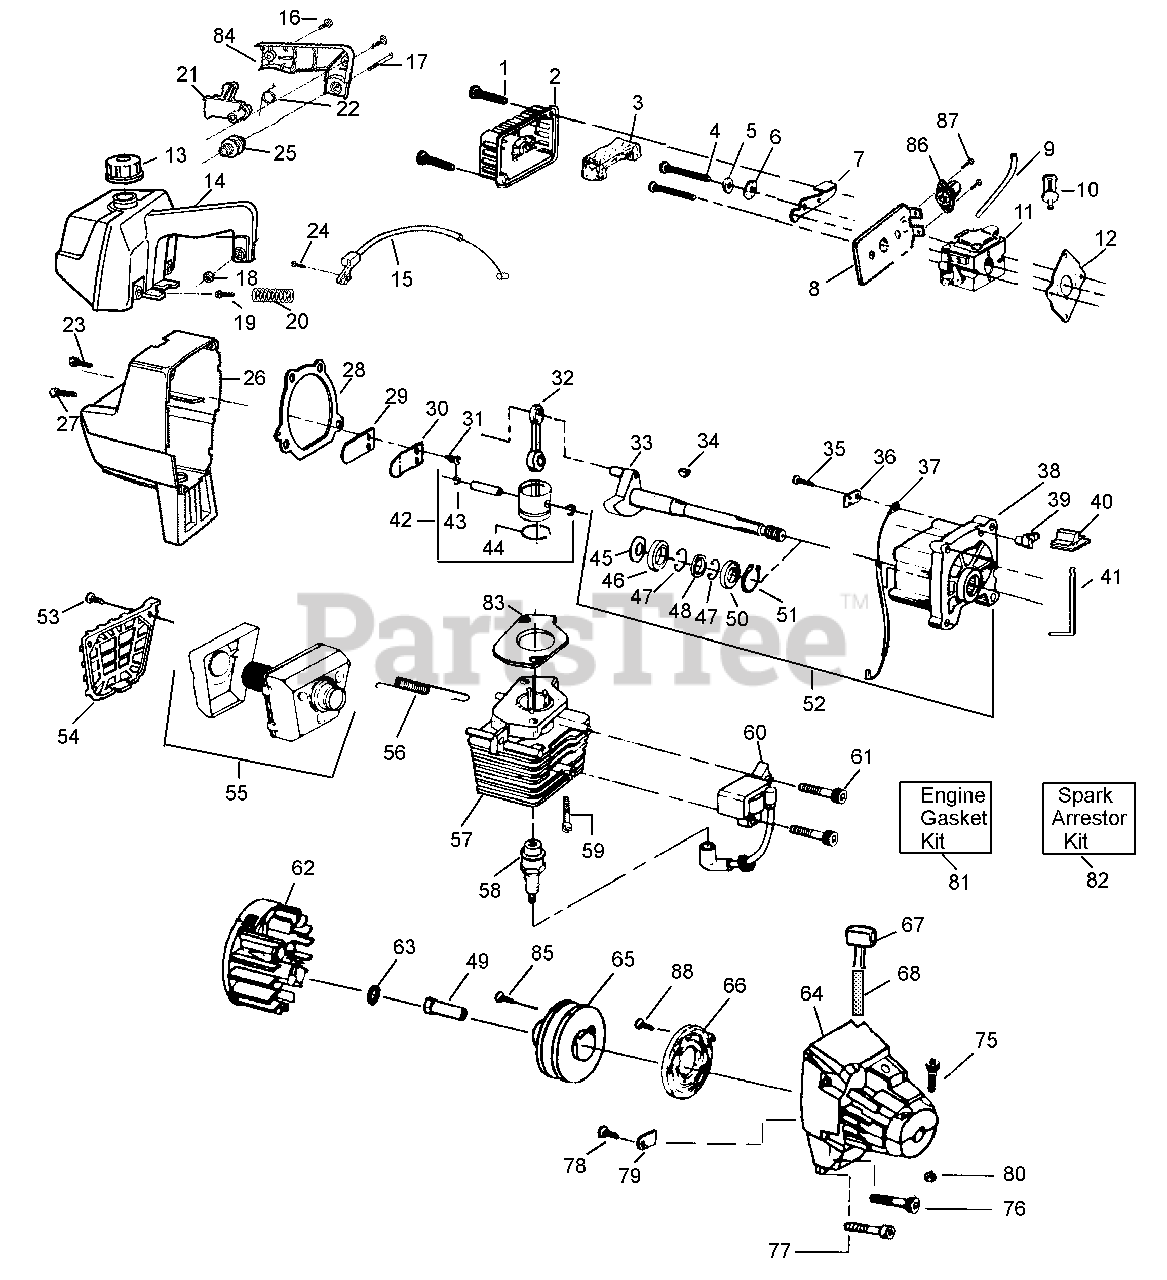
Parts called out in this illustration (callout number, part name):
2	Air Filter Cover
3	Air Filter
6	Wave Washer
7	Choke Shutter
8	Air Filter Plate Type 1
8	Air Filter Plate Type 2 & 3
9	Fuel Line Kit - Fuel Line
9	Fuel Line Kit - Return Line Type 2 & 3
10	Fuel Pick-up Ass'y.
11	Carburetor Type 1 (WA-217)
11	Carburetor Type 2 & 3 (WA-219B)
12	Carburetor Gasket
13	Fuel Cap Ass'y.
14	Handle & Tank Ass'y. Type 1
14	Handle & Tank Ass'y. Type 2 & 3
15	Throttle Cable Ass'y. Type 1
15	Throttle Cable Ass'y. Type 2 & 3
16	Screw
20	Rear Isolator Spring
21	Throttle Trigger
22	Throttle Spring
23	Screw
25	Isolator
28	Gasket
30	Reed Stop
32	Connecting Rod Ass'y.
33	Crankshaft Ass'y.
34	Flywheel Key
36	Switch Insulator
37	Lead Wire
38	Crankcase Ass'y.
39	Switch Ramp
40	Switch Button
41	Switch Spring
42	Piston Kit
43	Piston Pin Retainer
44	Piston Ring
45	Spacer
46	Inner Bearing
47	Retaining Ring
48	Crankshaft Seal
49	Drive Coupling
50	Outer Bearing
51	Crankshaft Retaining Ring
52	Crankcase & Crankshaft Ass'y.
54	Muffler Guard
55	Muffler Kit
56	Muffler Spring
57	Cylinder
58	Spark Plug Type 1 & 2 (CJ-14)
58	Spark Plug Type 3 (RCJ-8Y)
60	Ignition Module Kit
61	Screw
62	Flywheel Ass'y.
64	Fan Housing
65	Starter Pulley
66	Starter Spring
67	Starter Handle
68	Rope Kit
79	Pulley Retainer
81	Engine Gasket Kit
82	Spark Arrestor Kit
83	Cylinder Gasket
84	Handle Cover
85	Screw - Pulley
86	Primer Bulb Ass'y. Type 2 & 3
87	Screw - Primer Type 2 & 3
88	Screw - Starter Spring - Type 3
